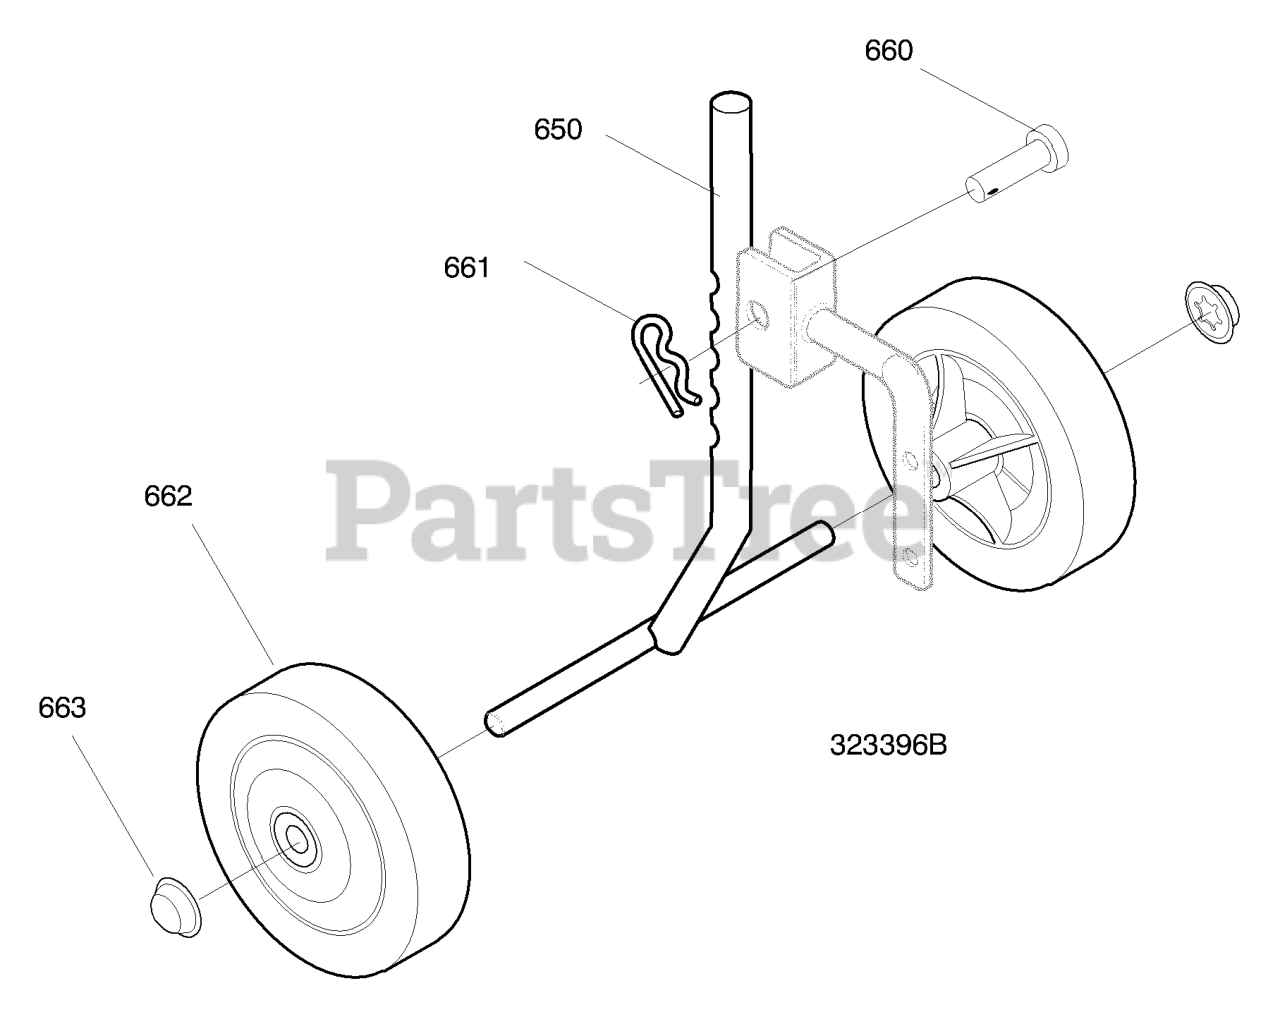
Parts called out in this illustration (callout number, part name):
650	Wheel Support Assy.
660	Clevis Pin
661	Hair Pin
662	Tire & Rim
663	Push On Nut
